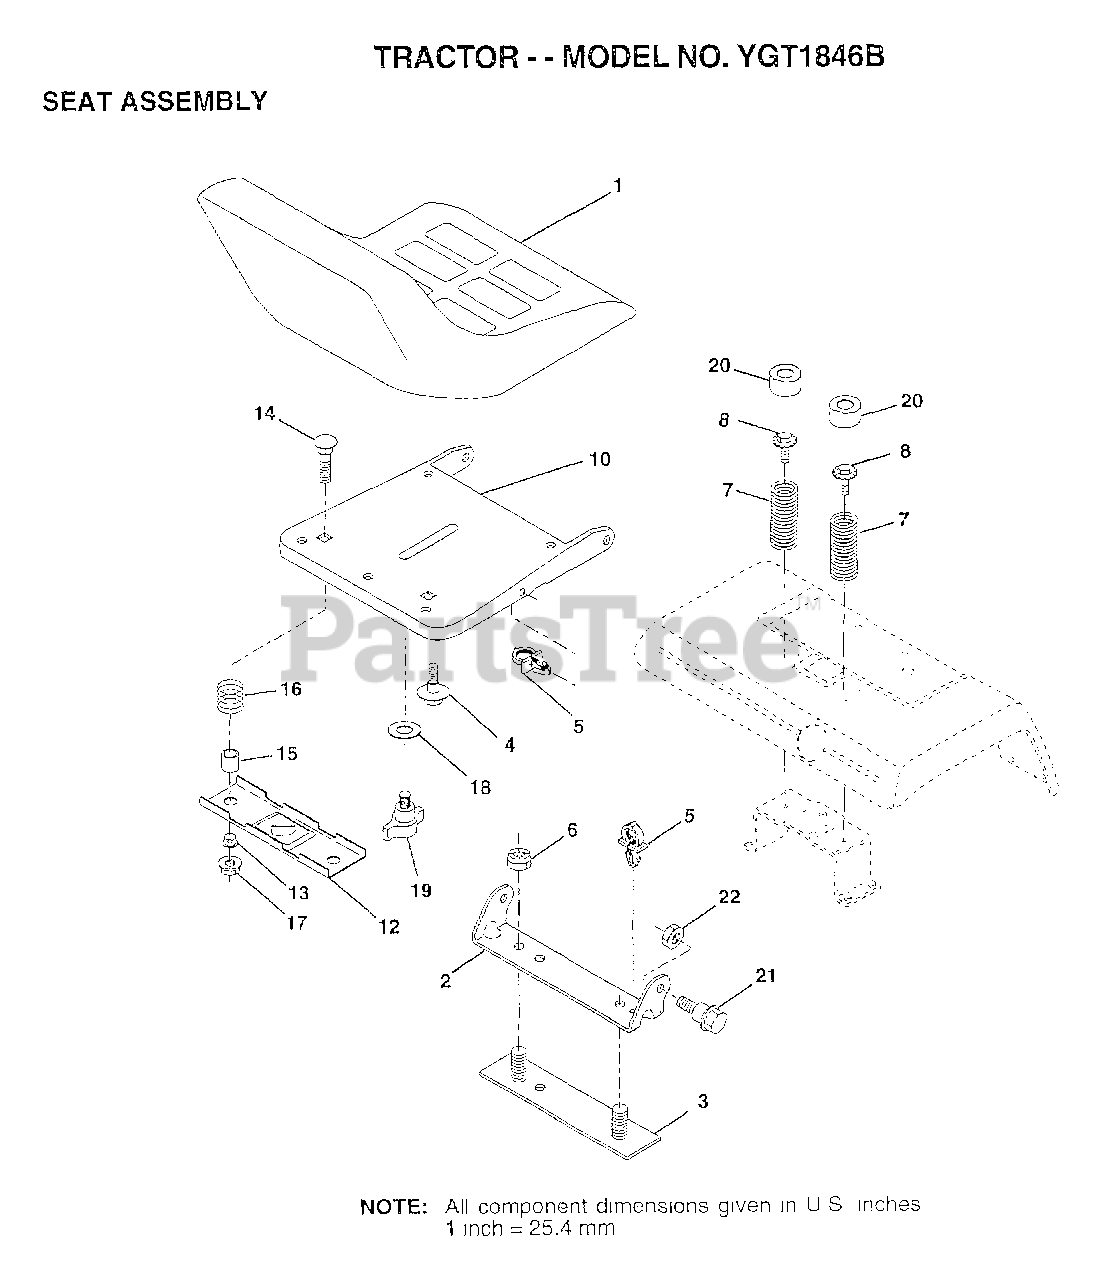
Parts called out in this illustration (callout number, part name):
2	BRACKET PVT SEAT
3	STRAP ASM FENDER
4	"BOLT,SHOULDER"
5	CLIP.PUSH-IN.HING
7	SPRING COMPRESSIO
8	BOLT.5/16-18.UNC
10	PAN-SEAT
12	BRKT SWITCH
13	BUSHING
14	BOLT-RD HD SQ NK
15	SPACER SPLIT
16	SPRING COMPRESSED
18	WASHER
19	KNOB.SEAT.ADJ.WINGNUT
20	CAP SPRING
21	"BOLT,SHOULDER"
